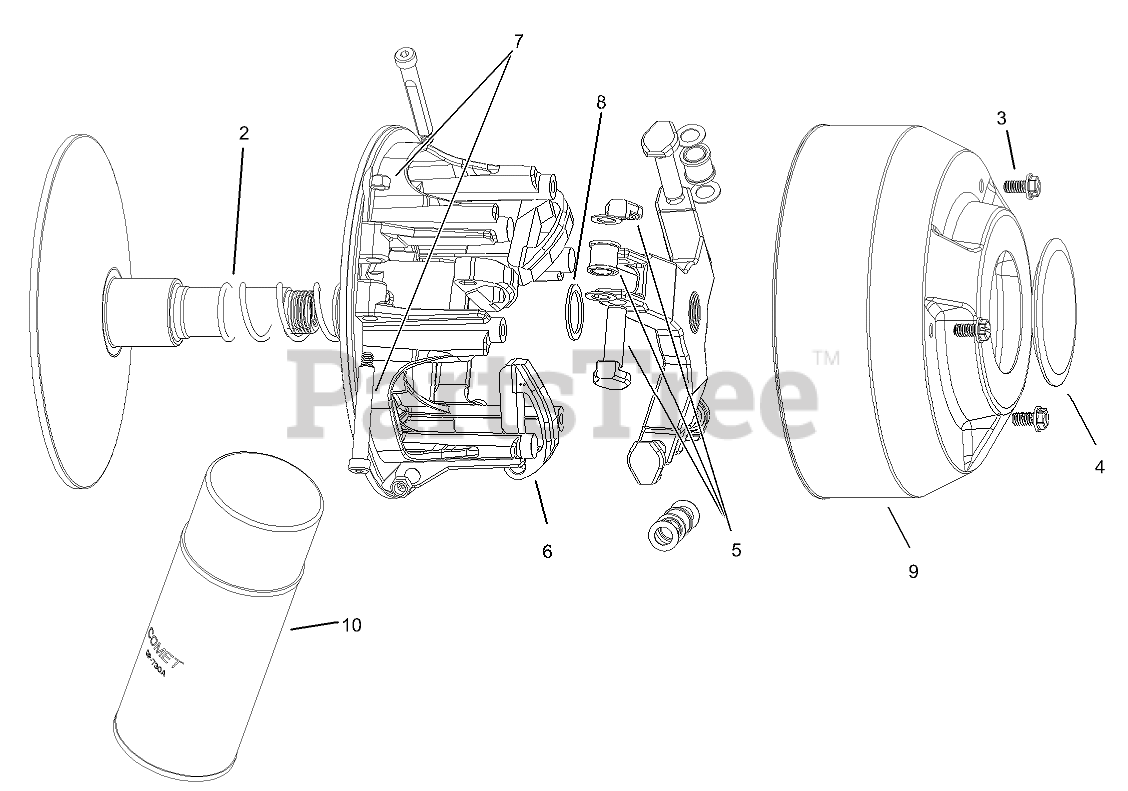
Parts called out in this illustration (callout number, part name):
2	SPRING
3	SCREW-HHF
5	SPIDER ASM
6	CAM-ARM
7	PIVOT BOLT AND NUT KIT
8	SPACER
9	COVER
10	LUBRICANT-DRY
